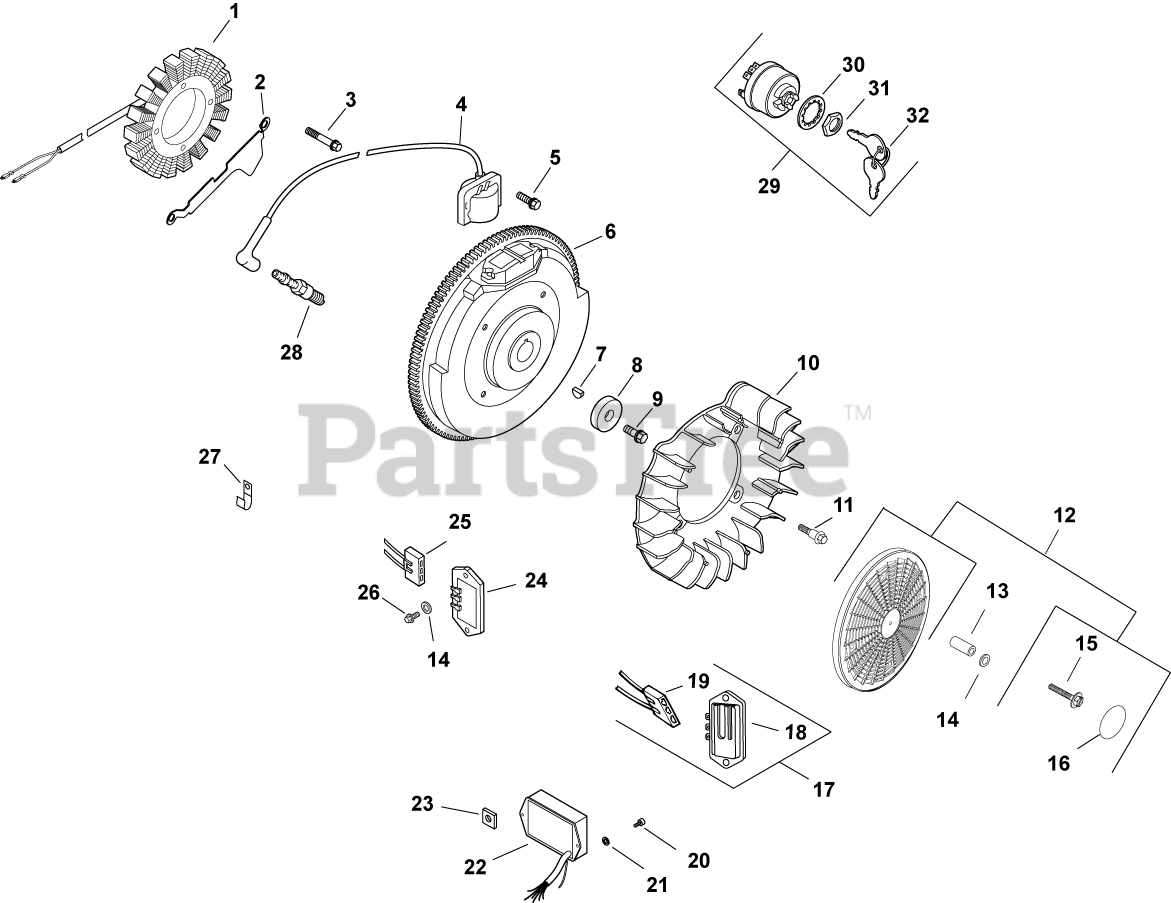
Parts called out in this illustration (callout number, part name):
1	KIT, 25 AMP STATOR ASSY.
2	BRACKET, STATOR WIRE
3	SCREW, THD FROM M5X0.8X30
4	MODULE, IGNITION
5	SCREW, SKT THD FRM M5X0.8X25
6	FLYWHEEL, PAINTED-USE 24 025 57-S
7	KEY, 3/16" X 5/8"
8	WASHER, FLAT 13/32"
9	SCREW, FLG M10X1.5X45 - (#25086361S)
10	FAN USE 24 157 11-S
11	BOLT, SHOULDER
12	KIT, GRASS SCREEN
13	SPACER - DISCONTINUED
14	WASHER, FLAT 3/16"
15	SCREW, FLG SEMS M4X.7X25
16	DECAL, GRASS SCREEN USE 24 113 499-S
17	KIT, FULL WAVE CONVERSION
18	REG-RECTIFIER (25 AMP)-USE 25 403 21-S
19	CONNECTOR, BODY (KM)-USE 25 155 41-S
20	SCREW, PHL HD #11-16X1/2"
21	WASHER, FLAT 1/4" (O.D. 1/2")
22	MODULE, SPEED ADVANCE-DISCONTINUED SEE PB265
23	NUT, PLASTIC
24	REG/RECTIFIER (20/25 AMP)-USE 25 403 20-
25	CONNECTOR, BODY (KM)-USE 25 155 41-S
26	SCREW, SLT HD CAP M4X0.7X25
27	CLIP, CABLE
28	PLUG, SPARK (STD)
29	SWITCH ASSY, KEY (KM)-USE 25 099 32-S
30	WASHER, INTERNAL TOOTH
31	NUT, KEY SWITCH
32	KEY, SET -USE 48 340 01-S
